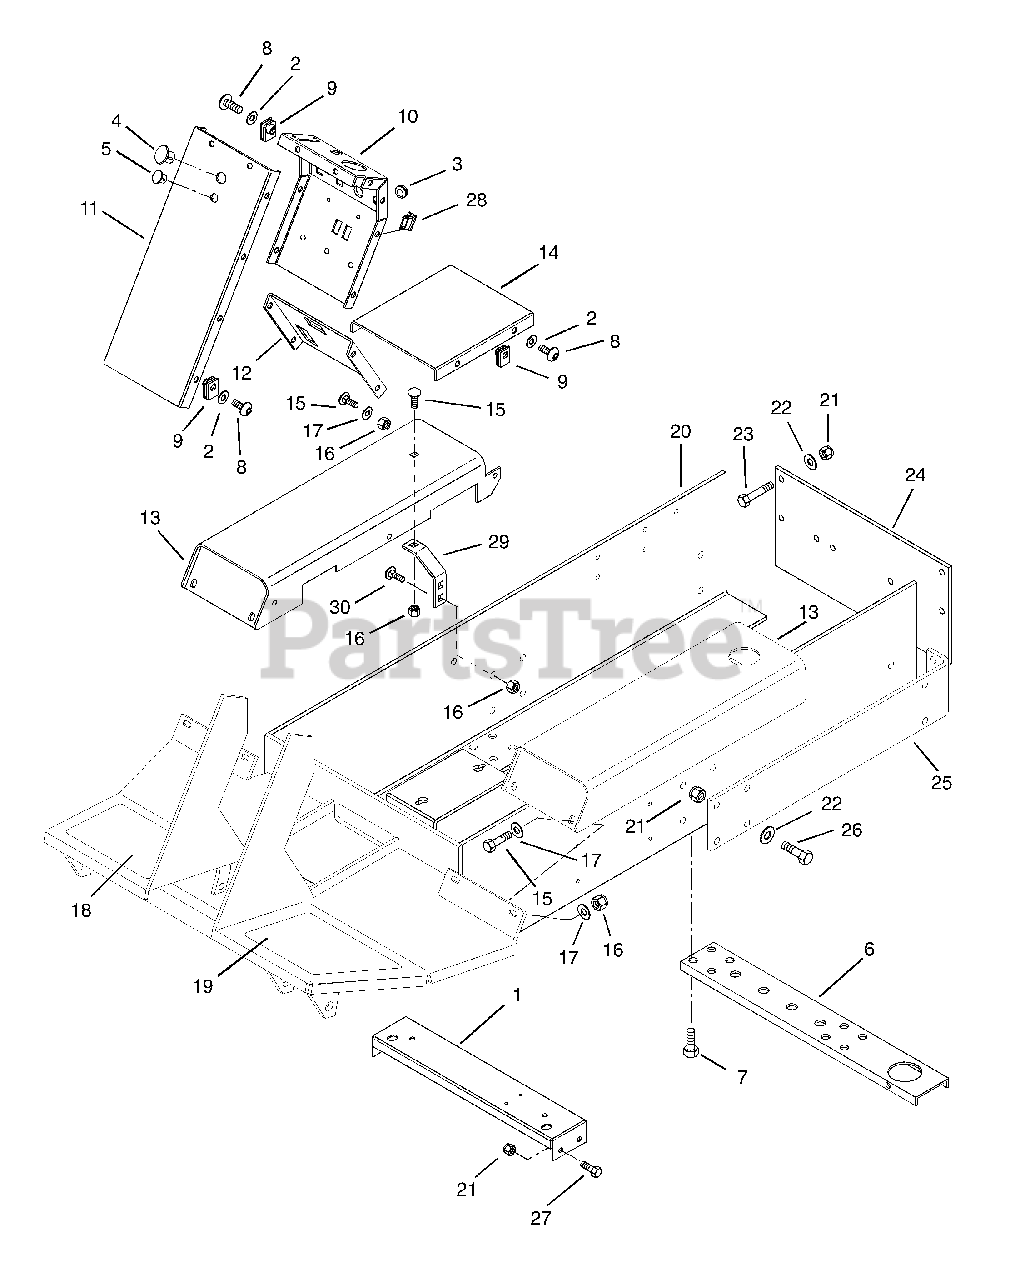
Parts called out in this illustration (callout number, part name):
1	Bracket, Deck Plate
2	Washer-Flat-Steel .281 x .62 x .065
3	Grommet .062 x .312
4	Hole Plug
5	Hole Plug
6	Brace, Frame
7	Bolt-Hex .38-16 x 1.25 Grade 5
8	Screw-Machine .25-20 X .75
9	Nut-Retainer .25-20 x .56
10	Panel, Instrument
11	Panel, Front
12	Panel, Brake Lock
13	Weldment, Fender Right Hand
13	Weldment, Fender Left Hand
14	Panel, Access
15	Bolt-Round Head Square Neck .38-16 x .75 Grade 5
16	Nut-Locking-Center .38-16
17	Washer-Flat-Steel .406 x .812 x .065
18	Cover, Right Hand Foot
19	Cover, Left Hand Foot
20	Weldment, Frame
21	Nut-Locking-Center .50-13
22	Washer-Flat-Steel .531 x 1.06 x .095
23	Bolt-Hex .50-13 x 1.50 Grade 5
24	Plate, Bumper-22 lbs
25	Bumper, Kubota Frame
26	Bolt-Hex .50-13 x 1.25 Grade 5
27	Bolt-Hex .50-13 x 1 Grade 5
28	Cover, Switch
29	Support, Fender
30	Bolt-Round Head Square Neck .38-16 x 1.00 Grade 5
